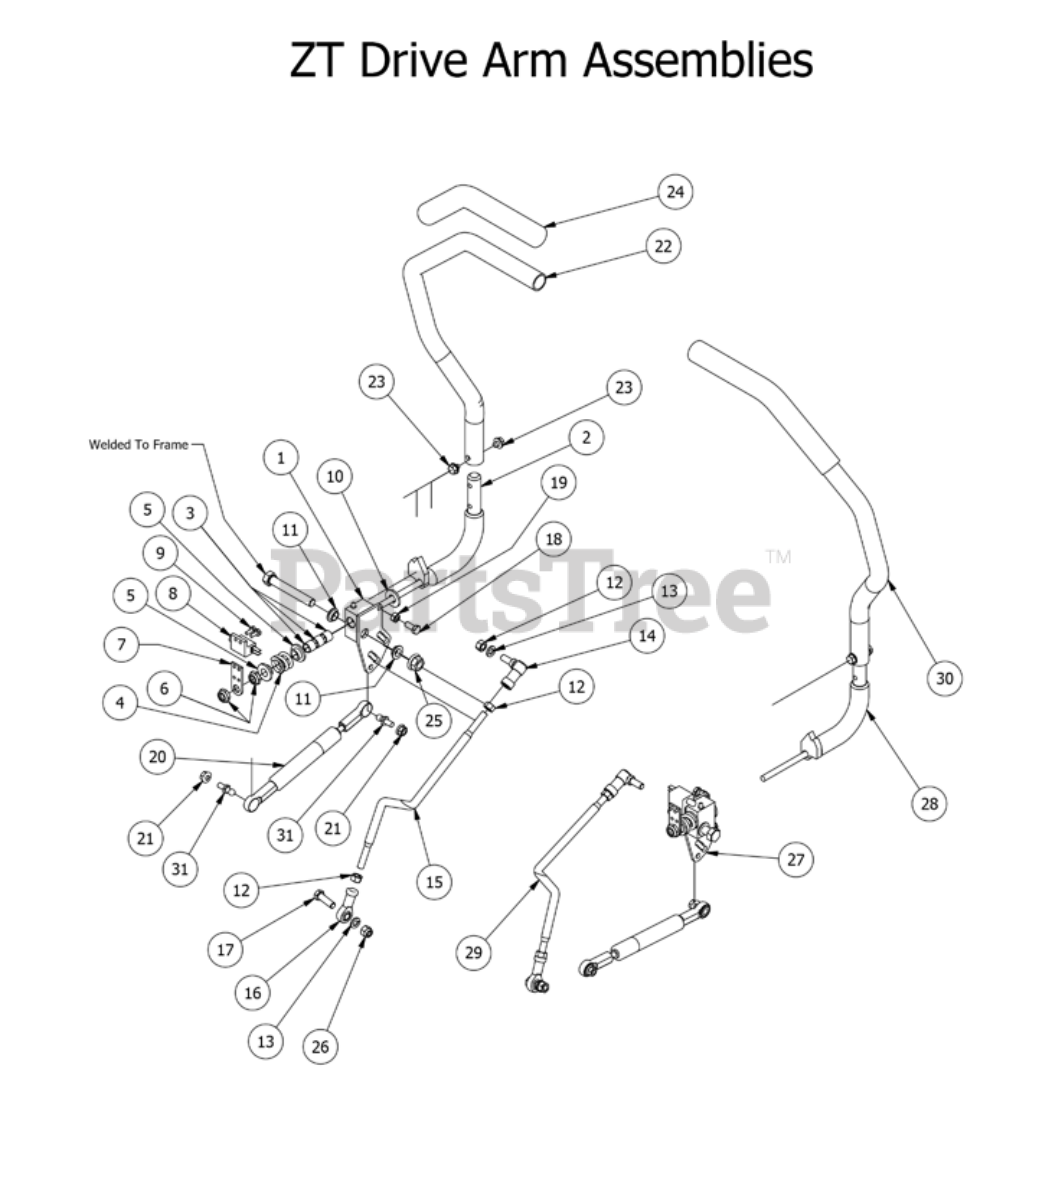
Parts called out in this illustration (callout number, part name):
1	2013 Drive Lever Housing (Left)
2	Steering Arm Elbow - Left
3	.507 ID Nylon Bushing
4	Drive Lever Spring
5	.515 ID Nylon Shoulder Washer
6	1/2" Nylcock Nut (1/2 Jam)
7	MZ Switch Bracket
8	Safety Switch
9	12-24x 1/2 HWH Bolt
10	.505 Nylon Spacer
11	1/2" Oil Impregnated Bushing
12	3/8" Fine Threaded Jam Nut
13	3/8" Lock Washer
14	3/8-24 Quick Release Ball Joint
15	Push Rod for ZT/CZT - Left
16	Spherical Rod End - Outlaw
17	3/8" x 1 1/4" Hex Bolt
18	5/16" x 3/4" Hex Bolt
20	Steering Damper For Outlaw
21	5/16" Flange Nut
22	ZT Direction Steering Arm (Left)
23	5/16-18 1/2 HWH Bolt-Steering
24	Rubber Grip
25	1/2-13 Hex Flange (GR.G) ZC
26	3/8 Nylock Nut
27	2013 Drive Lever Housing (Right)
28	Steering Arm Elbow - Right
29	Push Rod for ZT/CZT - Right
30	ZT Direction Steering Arm (right)
31	10mm Damper Ball Stud-Steering
